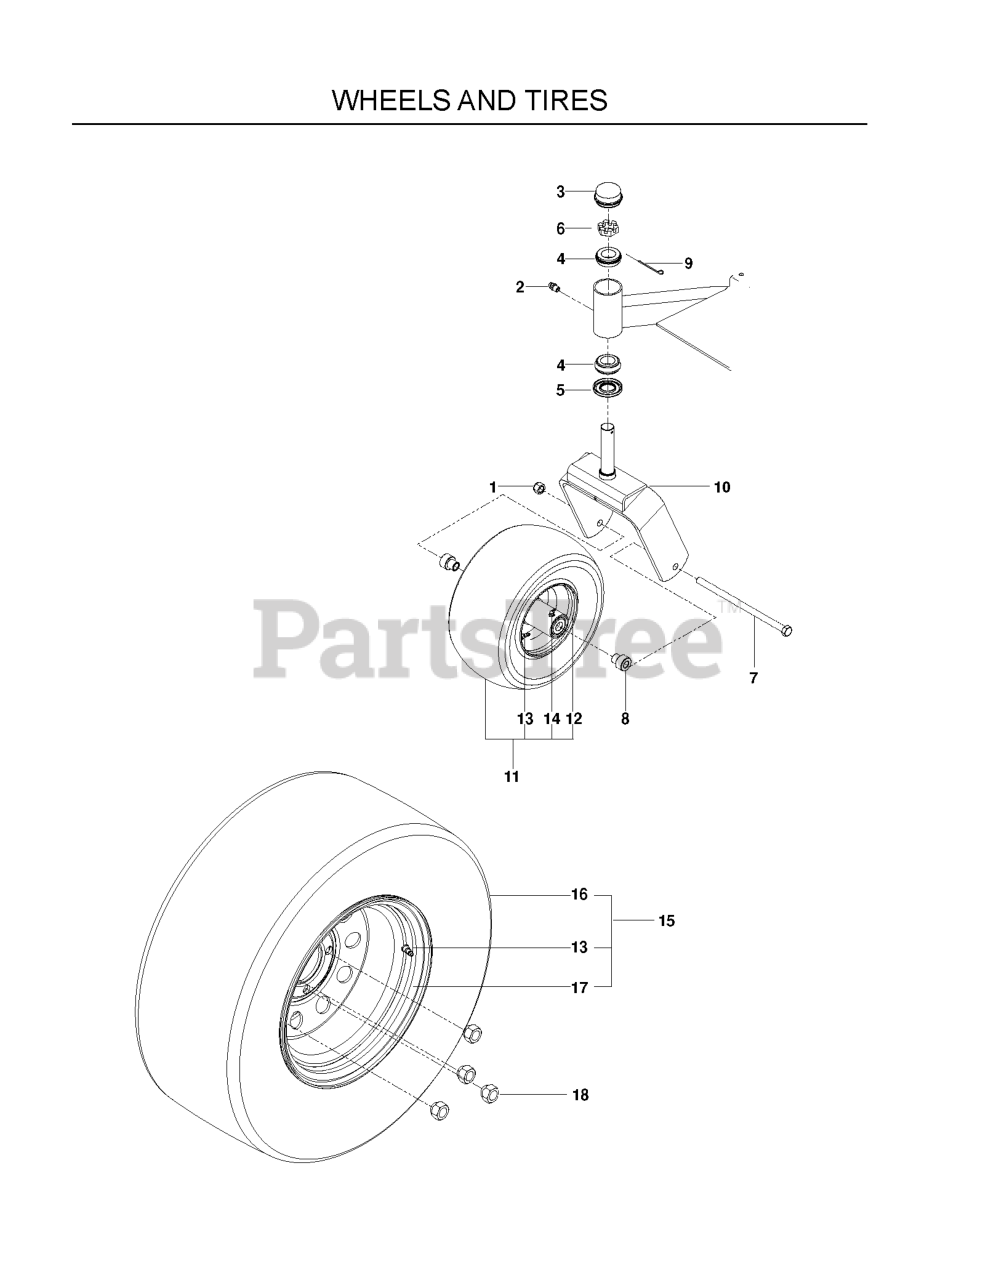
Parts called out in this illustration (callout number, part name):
1	NUT 1/2-13 HEX NYLOC ZD
3	GREASE CAP
4	TAPERED ROLLER BRG
6	NUT 1"C HEX SLOTTED
7	HEX SCREW 1/2-13 X 9.5 GR5
8	AXLE SPACER
9	COTTER PIN 1/8 X 2
10	CASTOR YOKE ORANGE
11	FRONT TIRE ASSY
13	VALVE STEM TR-412
14	ZERK
15	WHEEL/TIRE.ASM.23X9.5-12.GREY
16	TIRE.TURF.MASTER.23X9.5-12
17	RIM, 12 X 7, 1" NEG OFFSET
18	LUG NUT 1/2F
